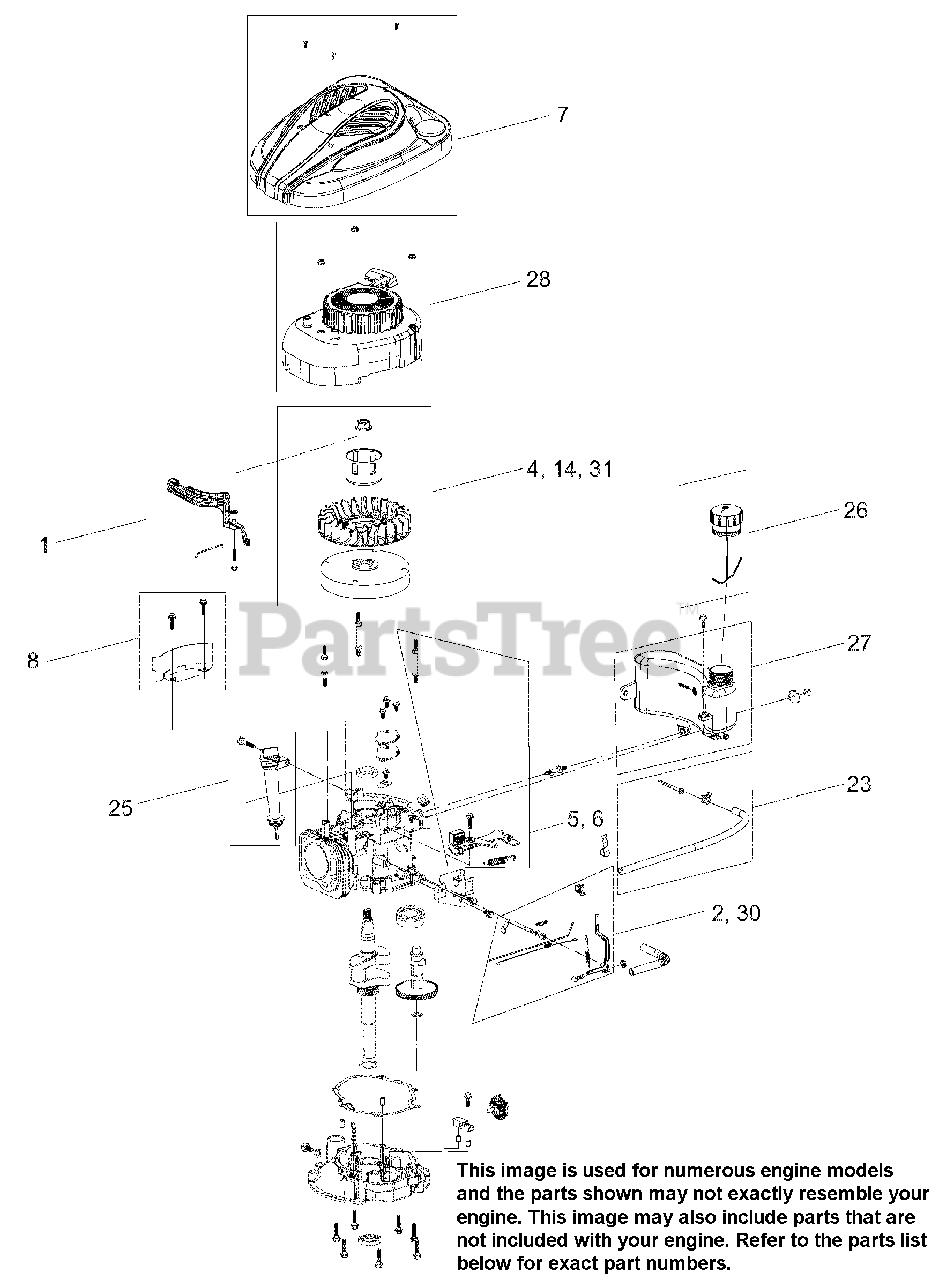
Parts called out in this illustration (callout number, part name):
1	KIT, AIR VANE CHOKE - SVC
2	GOVERNOR ARM KIT
3	KIT, MUFFLER AND SHIELD - SVC
4	FLYWHEEL AND FAN KIT - RECOIL START
5	KIT, BRAKE ASM RECOIL - SVC
6	KIT BRAKE ASSEMBLY - ELECTRIC
7	KIT, ARIENS STYLE - SVC
8	KIT, FLYWHEEL SHIELD - SVC
9	KIT, THERMAL CHOKE CONTROL-SVC
10	KIT, AIR CLEANER ASM - SVC
11	KIT, CARBURETOR COMPLETE - SVC
12	KIT, IGNITION COIL - SVC
13	KIT, SEAL AND GASKET - SVC
14	FLYWHEEL AND FAN KIT - ELECTRIC START
16	STARTER KIT - ELECTRIC START
17	KIT, WIRE HARNESS - SVC
18	KIT, VALVE COVER - SVC
19	LOCK, THROTTLE - SVC
20	STUD, INTAKE - SVC
21	ELEMENT, AIR CLEANER
22	FILTER, AIR - LONCIN 160CC
23	KIT, FUEL LINE W/FILTER - SVC
24	SPARK PLUG, LONCIN 160CC
25	DIPSTICK, OIL - SVC
26	CAP, FUEL - SVC
27	ASM, FUEL TANK W/HARDWARE
28	KIT, RECOIL - SVC
29	ENGINE, SERVICE, AC SERIES
29	ENGINE, SERVICE, AC SERIES, ELEC
30	KIT, GOVERNOR ARM (BBC)
30	KILL SWITCH, ENGINE, BBC
31	KIT, FLYWHEEL AND FAN (BBC)
